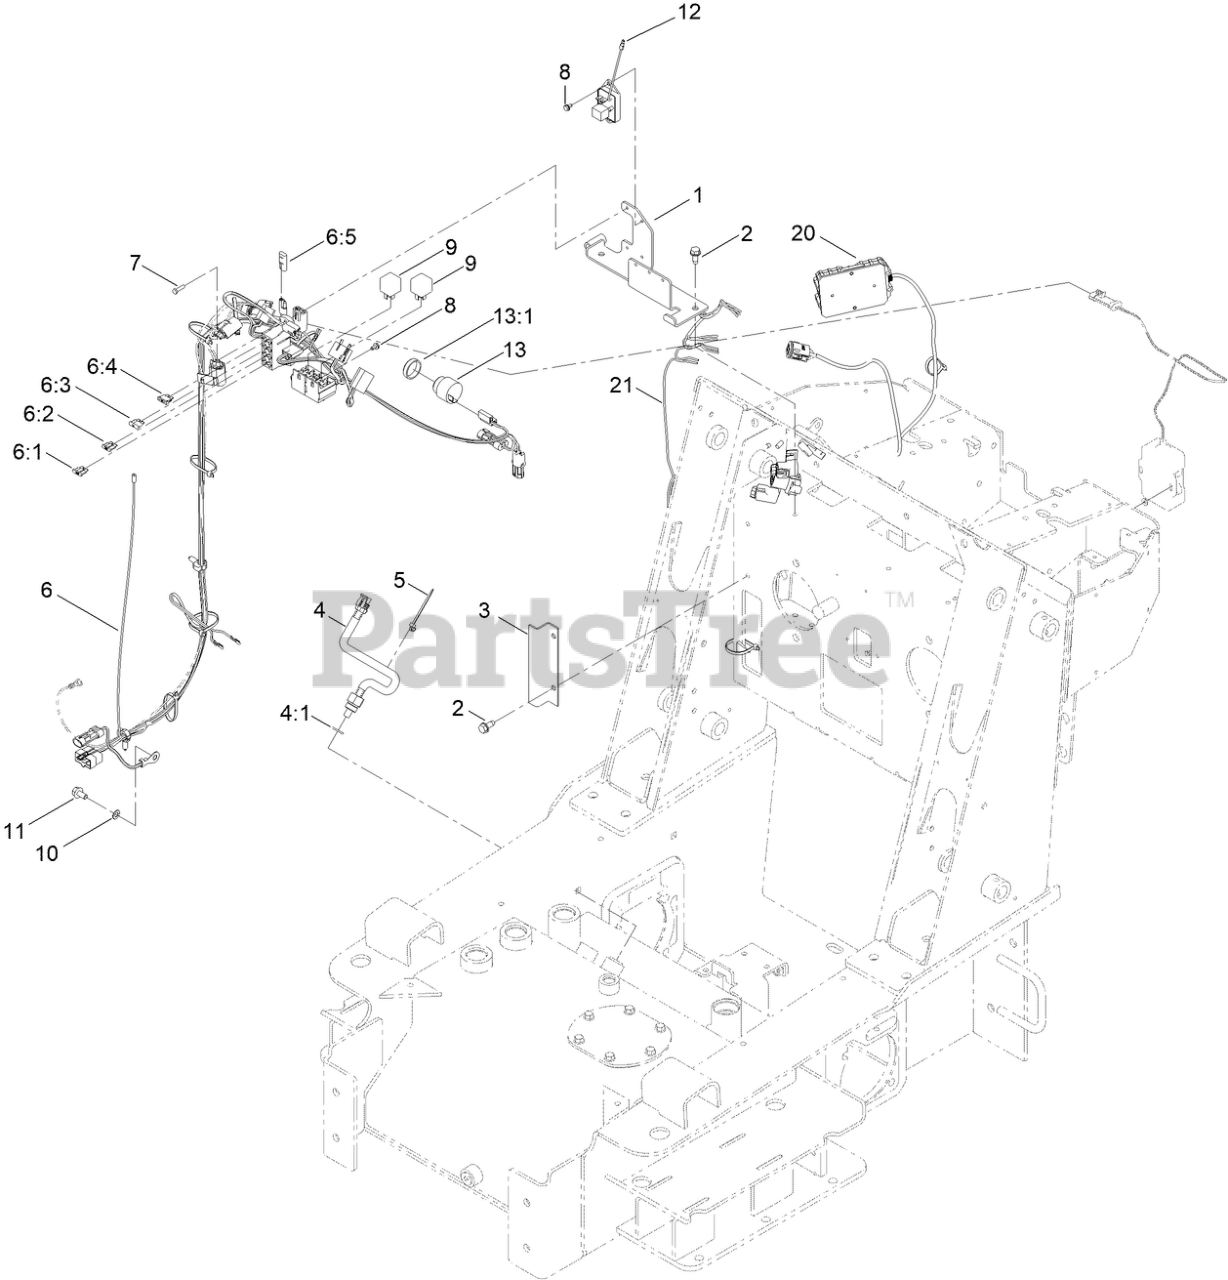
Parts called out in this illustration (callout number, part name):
1	BRACKET-FUSE/RELAY
2	SCREW-THD ROLL, HWH
3	SHIELD-WIRING
4	SWITCH-TEMPERATURE
4:1	O-RING
5	TIE-CABLE
6	HARNESS-WIRE
6:1	FUSE-BLADE, 30 AMP
6:2	FUSE-BLADE, 25 AMP
6:3	FUSE-BLADE, 10 AMP
6:4	FUSE-BLADE, 15 AMP
6:5	CAP-PLUG
7	SCREW
8	SCREW-HWH
9	RELAY
10	WASHER-LOCK
11	SCREW-HHF
12	MODULE-IGNITION DELAY
13	AUDIO ALARM ASM
13:1	NUT-PLASTIC, KNURLED
20	M7L-LITE ZTR KIT ASM
21	HARNESS-WIRE, MACHINE ZTR
